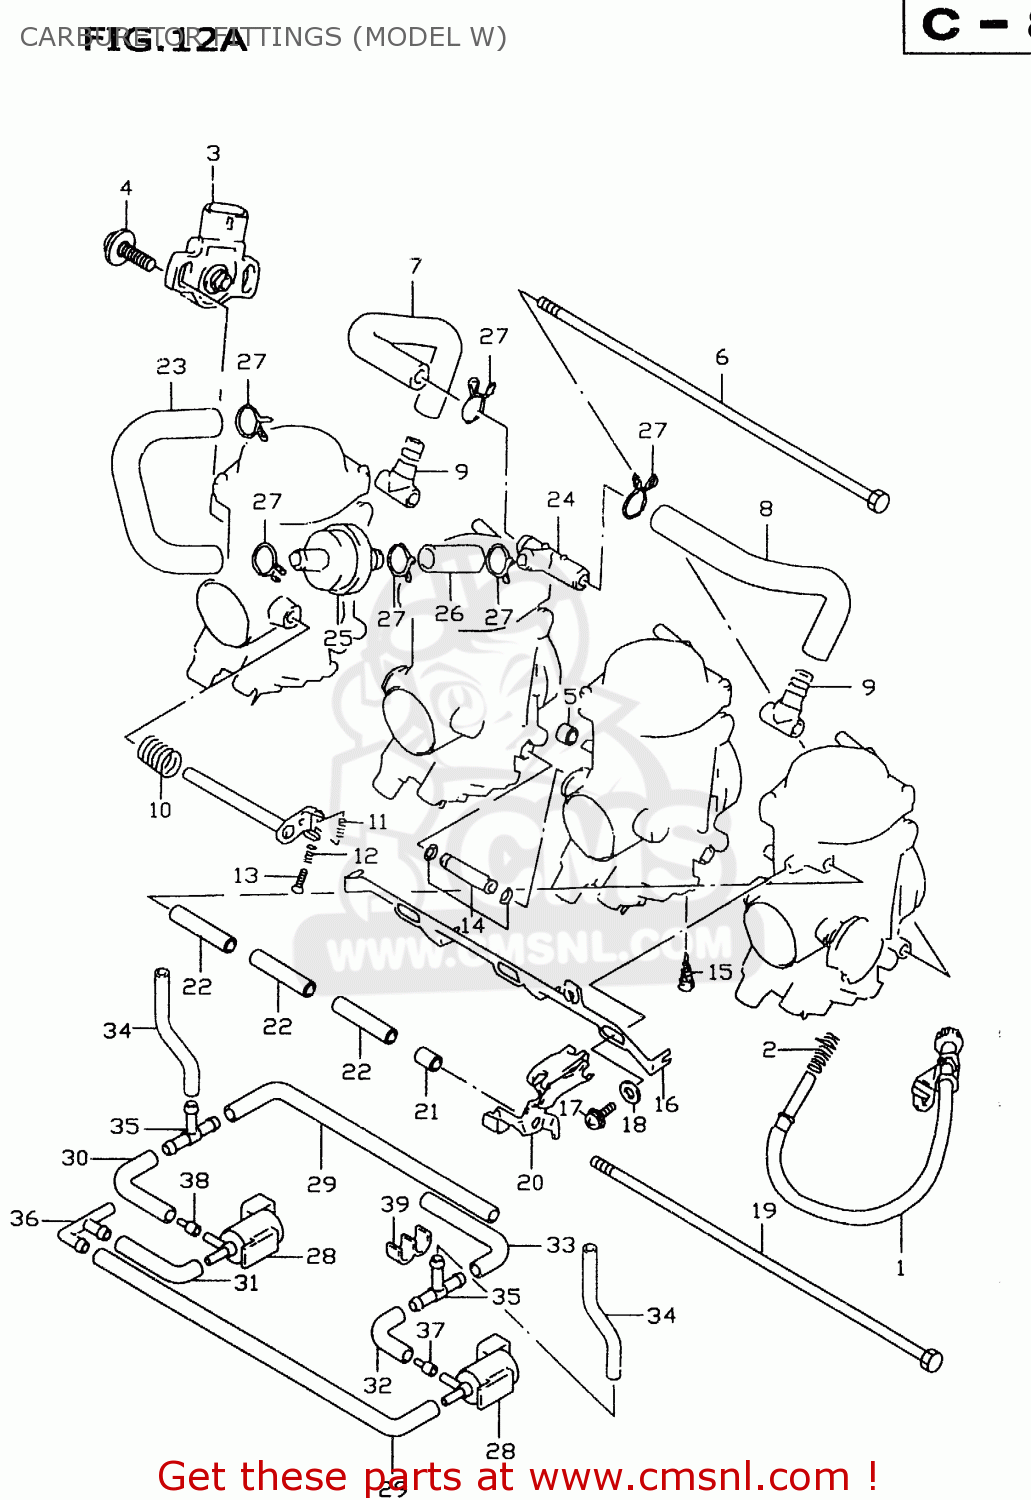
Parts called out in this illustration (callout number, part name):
1	ADJUSTER
2	SPRING
3	SENSOR ASSY,THROTTLE
4	SCREW, SENSOR
5	PIPE
6	BOLT
7	HOSE
8	HOSE
9	3 WAY
10	SPRING
11	SPRING,THROTTLE SCREW
12	SPRING
13	SCREW
14	NIPPLE,CARBURETOR
15	FILTER
16	LEVER,STARTER
17	SCREW
18	PACKING
19	BOLT
20	BRACKET
21	PIPE
22	PIPE
23	HOSE,AIR VENT(NO.1)
24	JOINT
25	FILTER,AIR VENT
26	HOSE(11X15X600)
27	CLIP
28	VALVE,PILOT AIR
29	HOSE(3X7X600)
30	HOSE(3X7X600)
31	HOSE(3X7X600)
32	HOSE
33	HOSE
34	HOSE
35	3 WAY
36	JOINT
37	JET,AIR (110)
38	JET,AIR(100)
39	CLAMP
